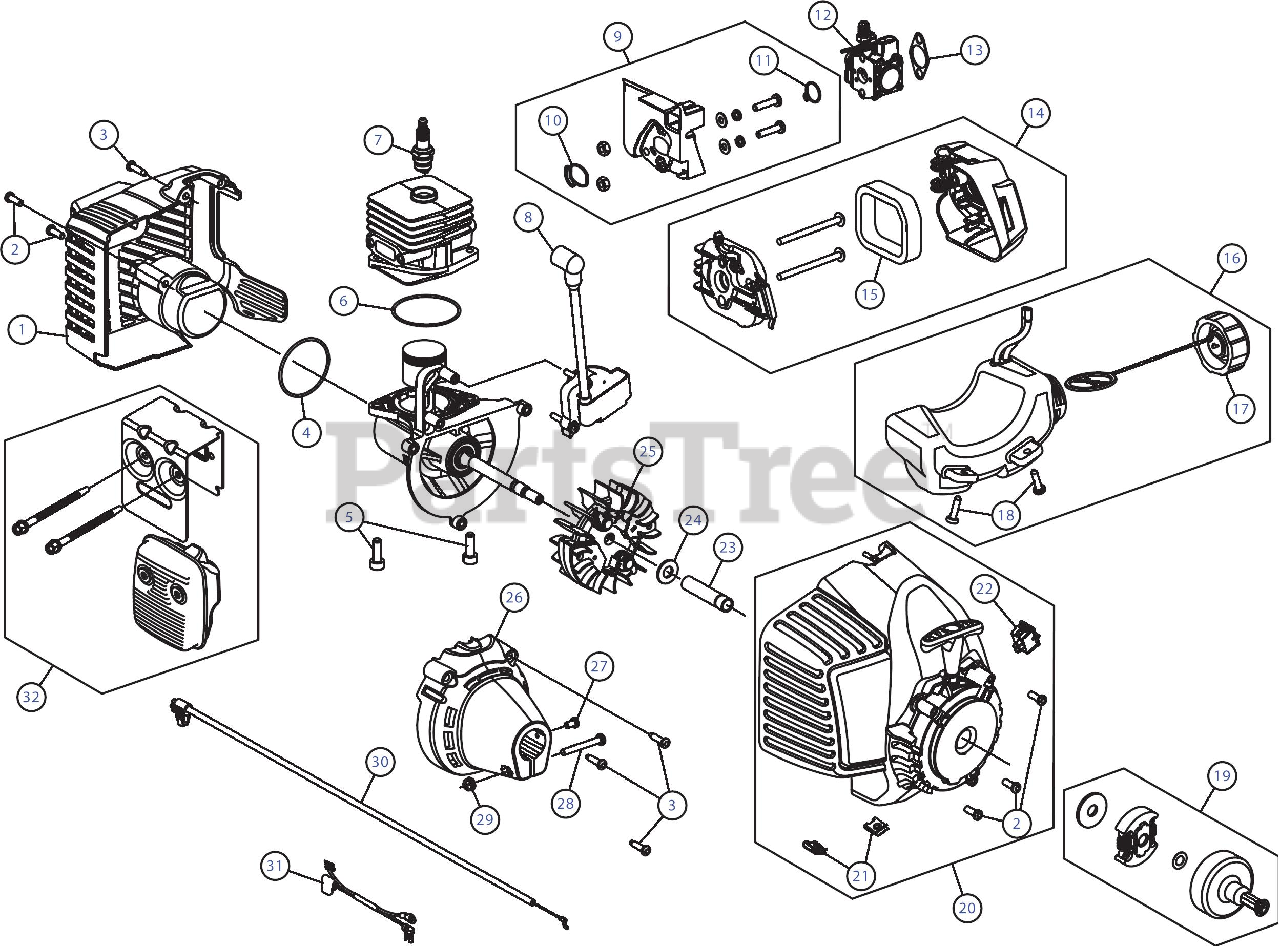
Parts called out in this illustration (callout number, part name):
1	Rear Cover Assembly
2	Housing Screw
3	Cover Screw
4	O-Ring
5	Crankcase Bolt
6	Crankcase O-Ring
7	Spark Plug
8	Module Assembly
9	Insulator Assembly
10	Insulator O-Ring
11	Carburetor O-Ring
12	Carburetor
13	Air Cleaner Gasket
14	Air Cleaner Cover Assembly
15	Air Cleaner Filter
16	Fuel Tank Assembly
17	Fuel Tank Cap
18	Fuel Tank Screw
19	Starter Clutch Assembly
20	Starter Housing
21	U-shaped Nut
22	Switch Assembly
23	Spacer
24	Washer
25	Flywheel Assembly
26	Clutch Cover
27	Anti-rotation Screw
28	Clamp Screw
29	Clamp Nut
30	Throttle Cable
31	Lead Wires
32	Muffler Assembly
